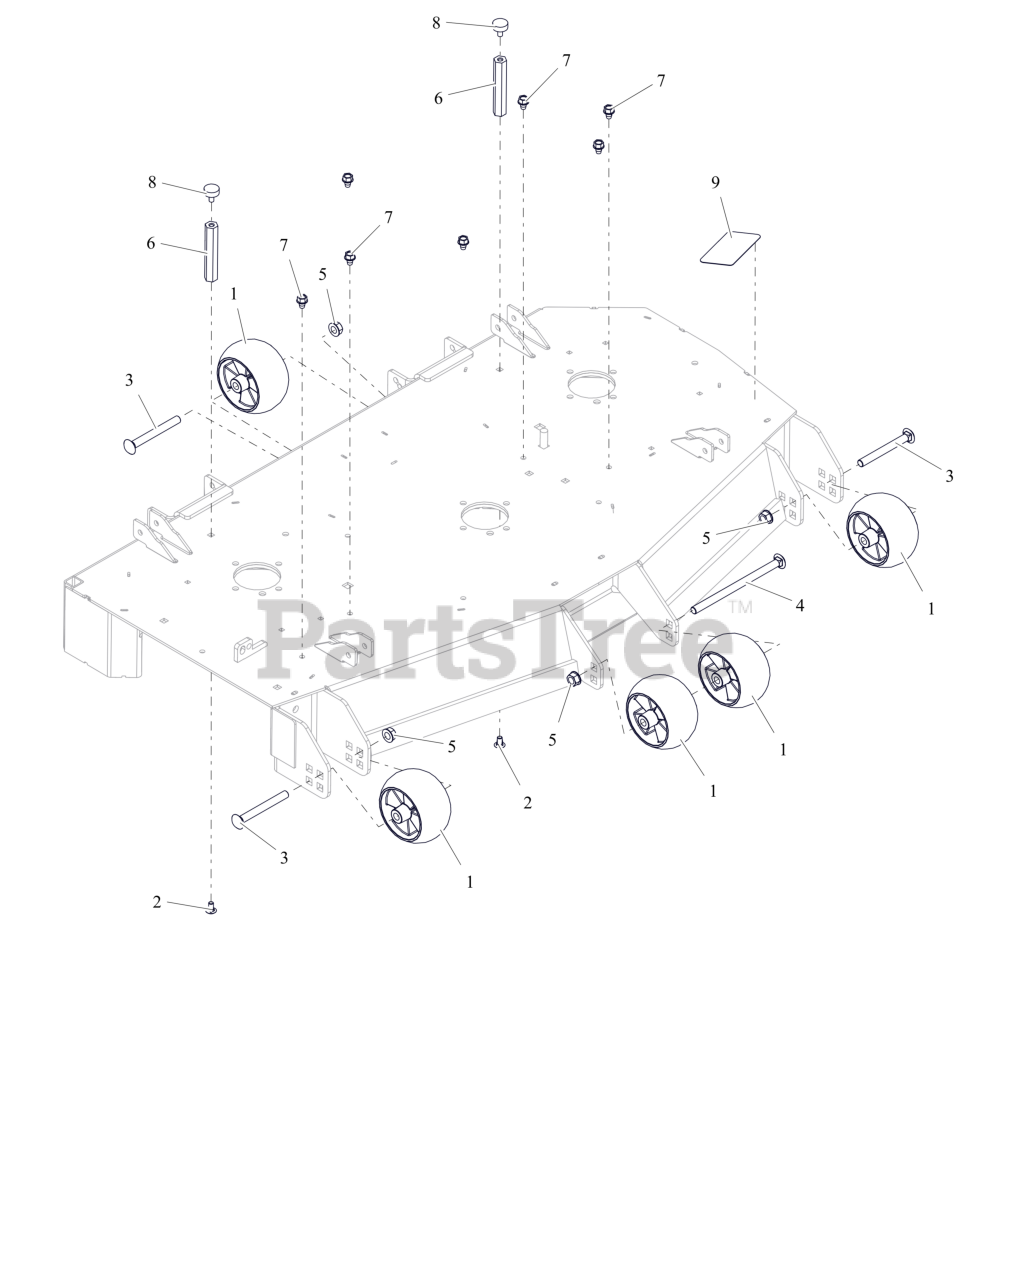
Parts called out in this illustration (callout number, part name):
1	WHEEL, ANTI SCALP - 5X3 CTR W/RIBS
2	BTL,RHSSN .313-18 X 0.625 G5 ZCC
3	BLT,RHNS .50-13X4.50 G5 ZCC NS
4	BLT,RHSN .50-13X8.00 G5 ZCC NS
5	NUT-LK-CTR-FLG .500-13 GG ZCC
6	NUT, COUPLING .312-18 X 4.295
7	SCR,TAP .375-16X.50 HWH TR ZCC
8	BUMPER, RUBBER
9	KIT, PT300-600 ANTI-SKID Tape
